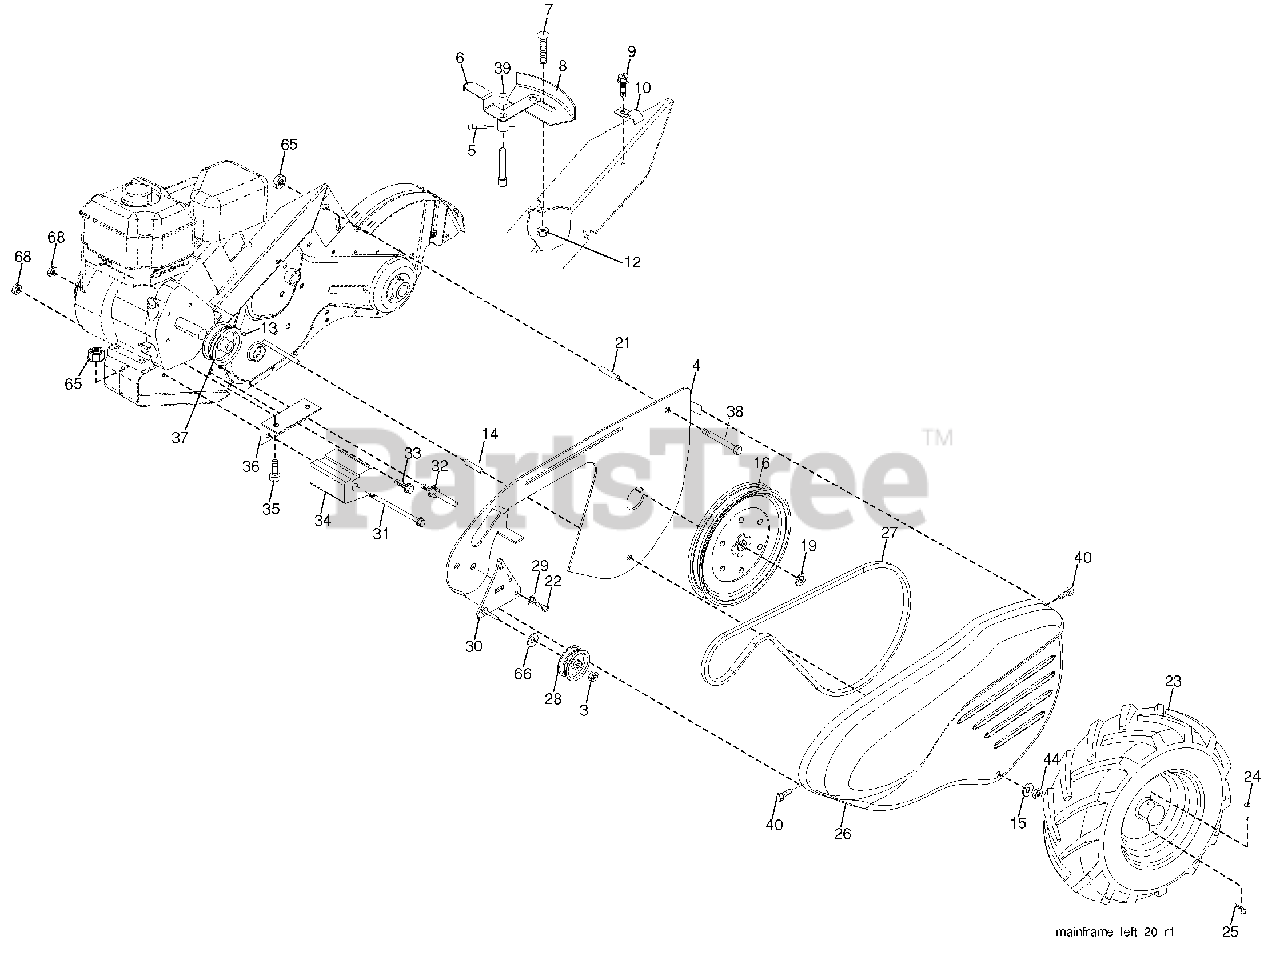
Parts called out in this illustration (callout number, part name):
3	Nut, Hex 3/8-16
4	Shield, Inner Belt Guard RT
5	Screw, Shift Lever
6	Lever, Shift
7	Bolt, Carriage 1/4-20 x 1/2 Gr. 5
8	Plate, Shift Indicator
9	Screw, Hex, Washer Head, Slotted #10-24 x 1/2
10	Clip
12	Nut, Keps Hex 1/4-20 unc
13	Screw, Set, Hex 5/16-18 x 3/8
14	Spacer, Split 0.327 x 0.42 x 1.220
15	Washer 11/32 x 11/16 x 16 Ga.
16	Sheave, Transmission
19	Retainer, Ring
21	Spacer, Split 0.327 x 0.42 x 2.09
22	Bolt, Fin Hex 5/16-24 unf x 1/2
23	Tire
23	Rim
23	Tire Valve
24	Rivet, Drilled
25	Clip, Hairpin
26	Guard, Belt
27	Belt, V
28	Pulley, Idler
29	Ring, Klip
30	Bracket, Idler
31	Bolt, Hex 5/16-16 x 12
32	Shaft, Idler Arm
33	Bolt, Hex 3/8-16 x 1
34	Counterweight, L. H.
35	Bolt, Hex 5/16-18 x 1-3/4
36	Bracket, Reinforcement, L. H.
37	Sheave, Engine
38	Bolt, Fin Hex 5/16-18 unc x 2-3/4
39	Cap, Plunger Blk
40	Screw Hex Wsh Slt #10-24 x 1/2
44	Nut Lock Hex w/Ins 5/16-18 unc PL
65	Nut Lock Hex Flange
66	Washer 13/32 x 13/16 x 12 Ga.
68	Nut Keps Hex 3/8-16 unc
